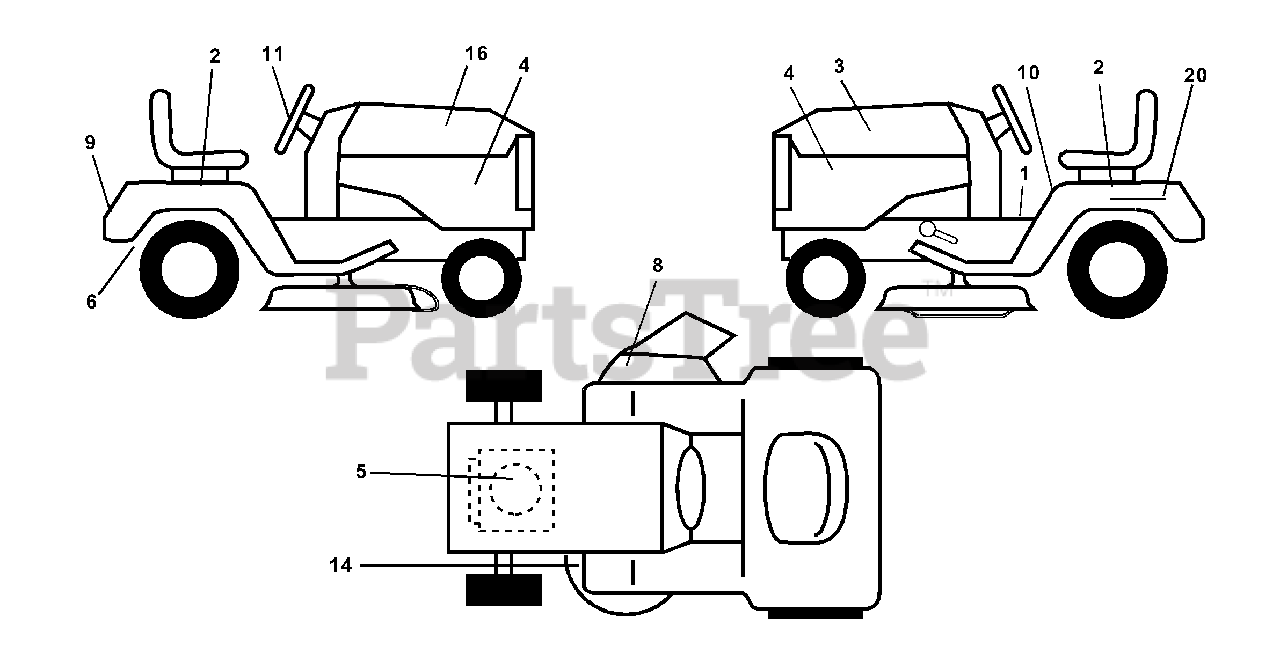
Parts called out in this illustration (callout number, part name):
1	Decal Oper
2	Decal Fender Auto
3	Decal Hood LH
4	Decal Side Panel Logo
5	Decal HP Engine
6	Decal By Pass Lt Hydro
8	Decal Mower Warn Keep Hand Away
9	Decal Fender Logo
10	Decal Fender Danger E/F
11	Decal Ins Strg Whl
14	Decal V-Belt Schematic
16	Decal Hood Rh
20	Decal Bat Dan/Psn
